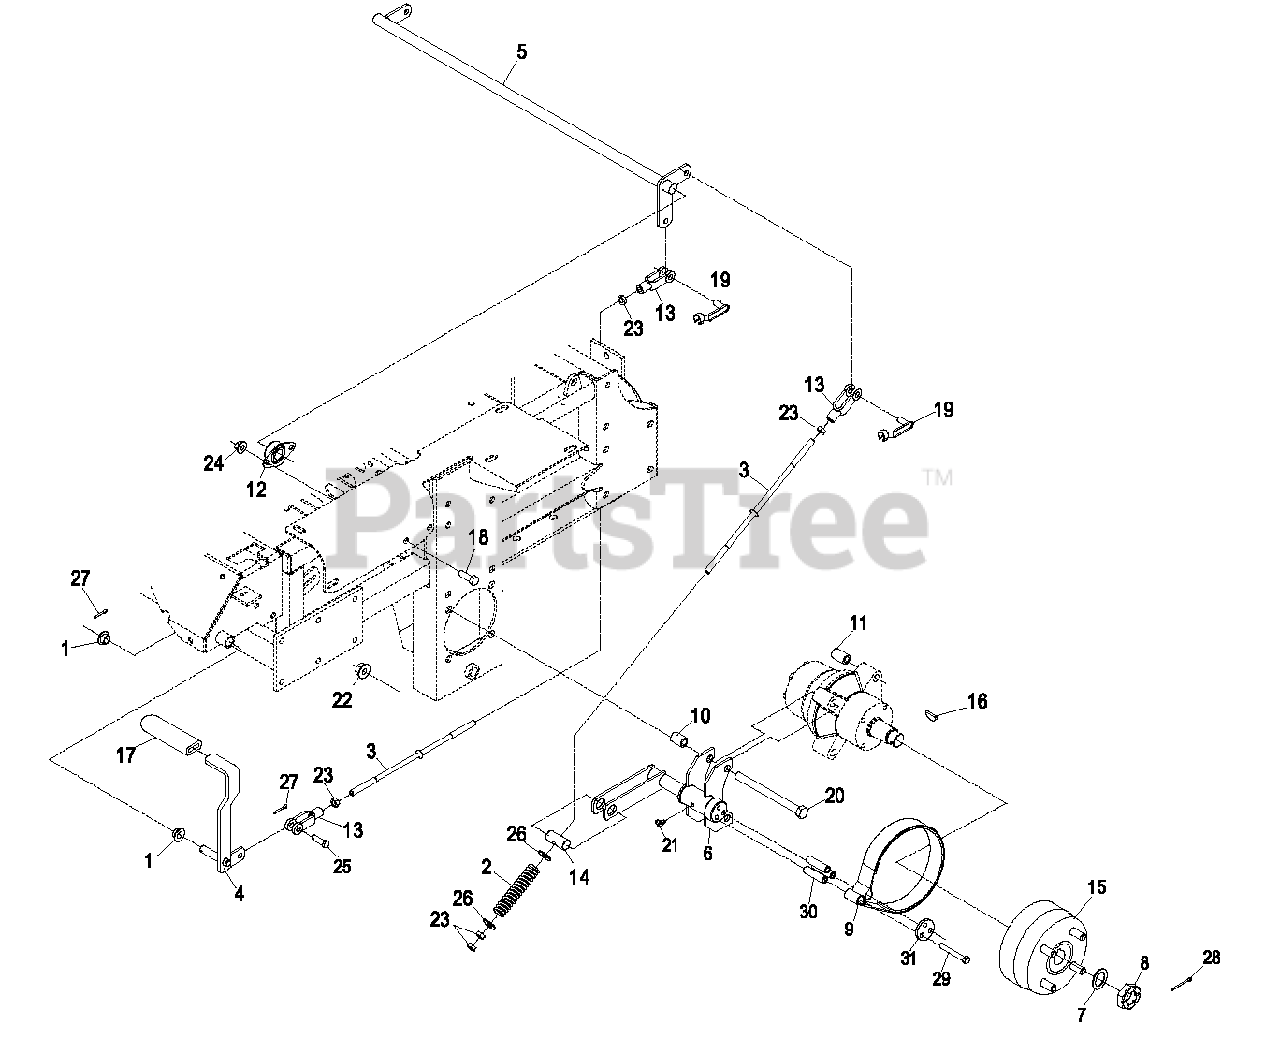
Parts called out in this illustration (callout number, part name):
1	BEARING-CONTROL
2	SPRING-BRAKE
3	ROD-BRAKE
4	BRAKE LEVER ASM
5	SHAFT-BRAKE
6	BRACKET-BRAKE
6	BRAKE BRACKET ASM
7	WASHER-SPACER
9	BAND,BRAKE
10	SPACER-WHEEL, SHORT
11	SPACER-WHEEL, LONG
12	BEARING-FLANGE, SIDE
13	YOKE-LINKAGE, BRAKE
14	PIN-TRUNION
15	WHEEL HUB ASM
16	KEY-WOODRUFF
17	GRIP-LEVER
18	SCREW-HH
19	PIN-SPRING, CLEVIS
20	SCREW-HH
21	FITTING-STRAIGHT
22	NUT-HHF
23	NUT-HEX
24	NUT-HHF, WHIZ
25	PIN-CLEVIS
26	WASHER-FLAT
27	PIN-COTTER
28	PIN-COTTER
29	SCREW-HH
31	RETAINER-BAND, BRAKE
